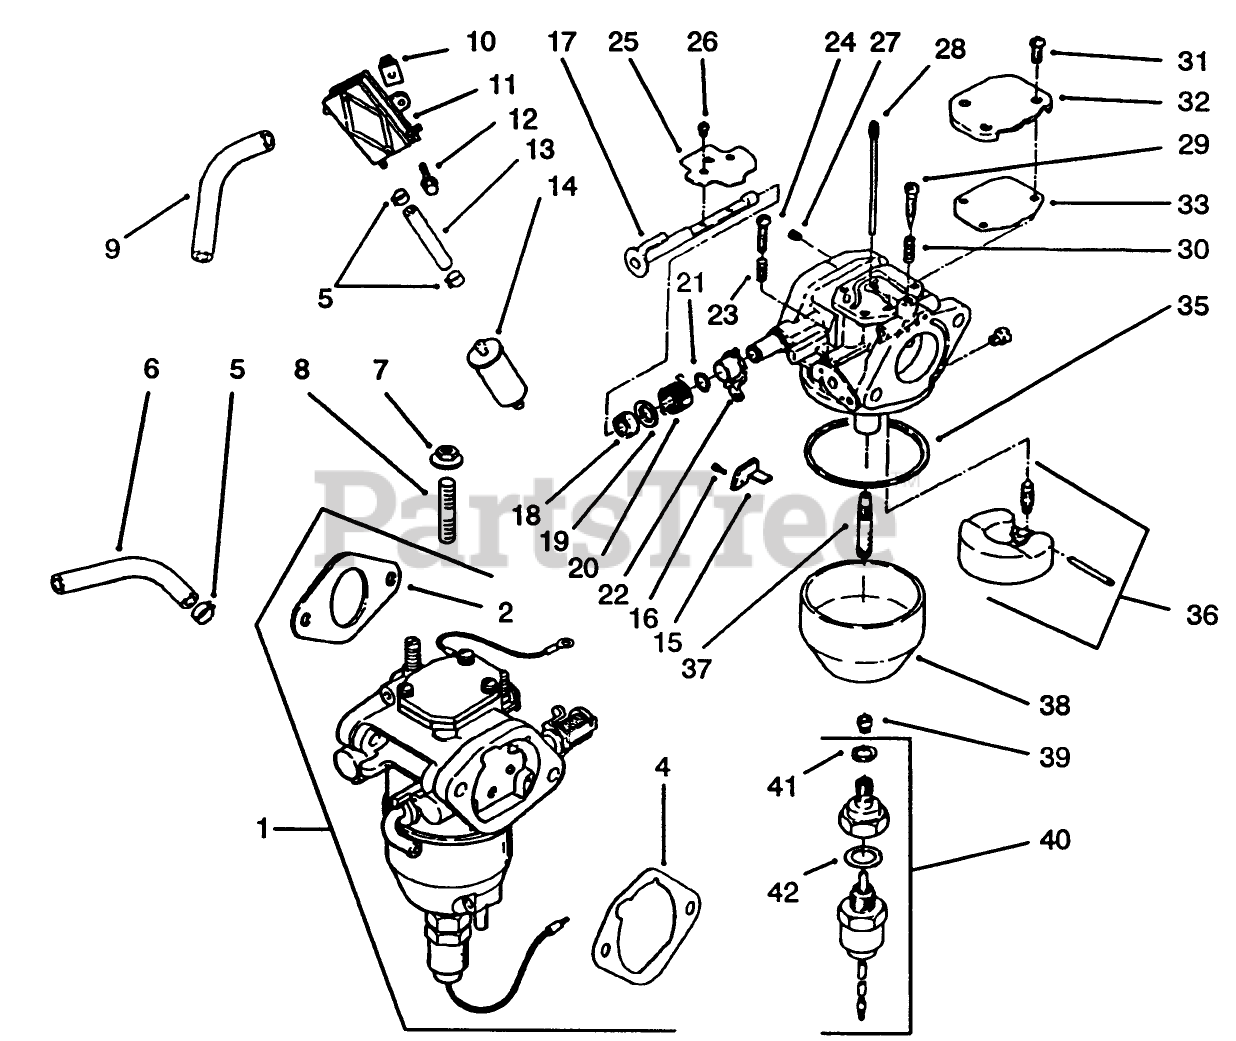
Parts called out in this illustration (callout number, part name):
1	Kit-Carb INCL 2/4/15-42 (Only On: 72103)
2	Gasket-Carburetor (Only On: 72103)
4	Gasket-A/C Base (Only On: 72103, 72083)
5	Clamp
6	Line-Fuel 10 1/2" (Only On: 72103, 72083)
8	Stud M6x1.0x95 (Only On: 72103, 72083)
9	Line-Fuel 12" (Only On: 72103)
11	Pump-Fuel
13	Line-Fuel 3 1/2" (Only On: 72103)
14	Filter-Fuel (Only On: 72042,72043,72062,72063)
15	Bracket-Throttle Stop (Only On: 72103, 72083)
16	Screw M2.5X45X5.5 (Only On: 72103)
17	Shaft-Choke (Only On: 72103, 72083)
18	Washer (Only On: 72103, 72083)
19	Collar-Choke (Only On: 72103, 72083)
20	Spring-Choke Return (Only On: 72103, 72083)
21	Ring-Choke Lever (Only On: 72103)
22	Lever-Choke (Only On: 72103)
23	Spring-Throttle Screw (Only On: 72103, 72083)
24	Screw-Throttle Adjust (Only On: 72103, 72083)
25	Valve-Choke (Only On: 72103)
26	Screw-Throttle Shaft (Only On: 72103, 72083)
27	Jet-Air Bleed (Only On: 72103)
28	Jet-Slow (Only On: 72103)
29	Screw-Idle Adjust (Only On: 72103, 72083)
30	Spring-Idle Adjust Screw (Only On: 72103)
31	Screw (Only On: 72103)
32	Cover-Passage (Only On: 72103, 72083)
33	Gasket-Passage Cover (Only On: 72103, 72083)
35	Gasket-Float Chamber (Only On: 72103)
36	Kit-Float Repair (Only On: 72103)
37	Nozzle-Main (Only On: 72103,72083)
38	Chamber-Float (Only On: 72103)
39	Jet-Main (Only On: 72103)
40	Kit-Solenoid INC 41-42 (Only On: 72103, 72083)
41	Gasket-Chamber Screw (Only On: 72103)
42	Gasket-Solenoid (Only On: 72103, 72083)
